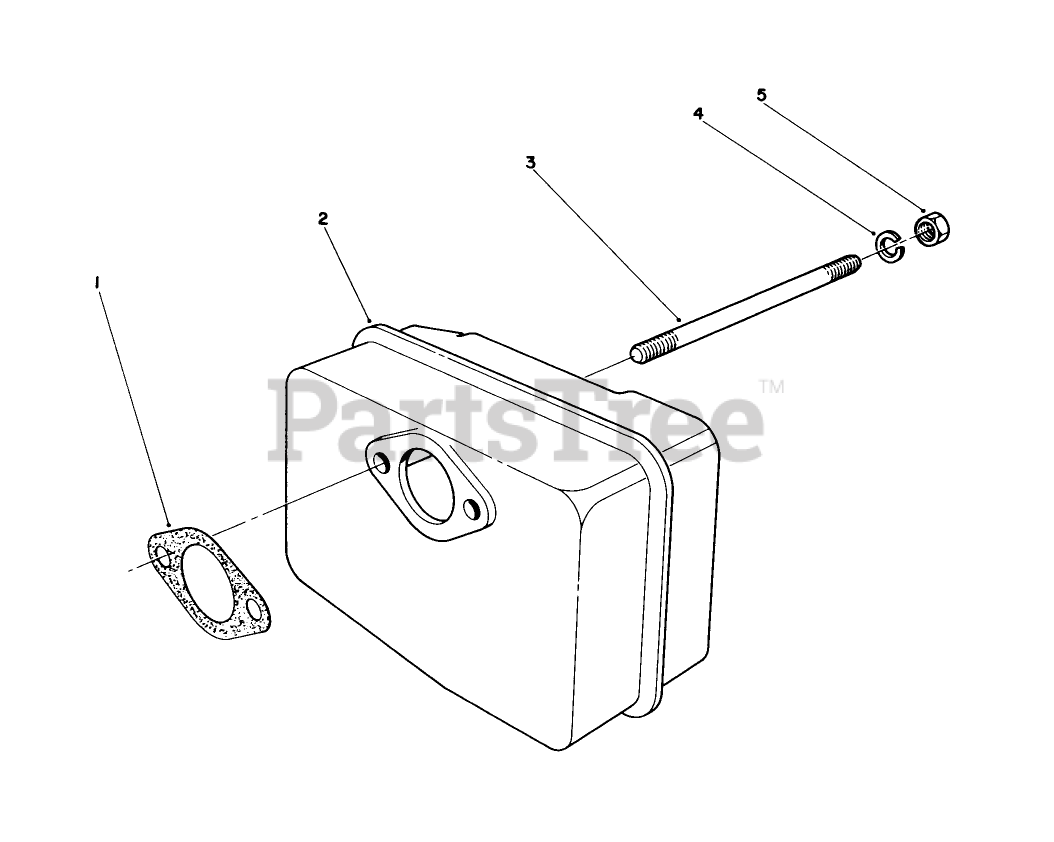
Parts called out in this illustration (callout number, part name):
1	GASKET
2	MUFFLER
4	WASHER-LOCK
